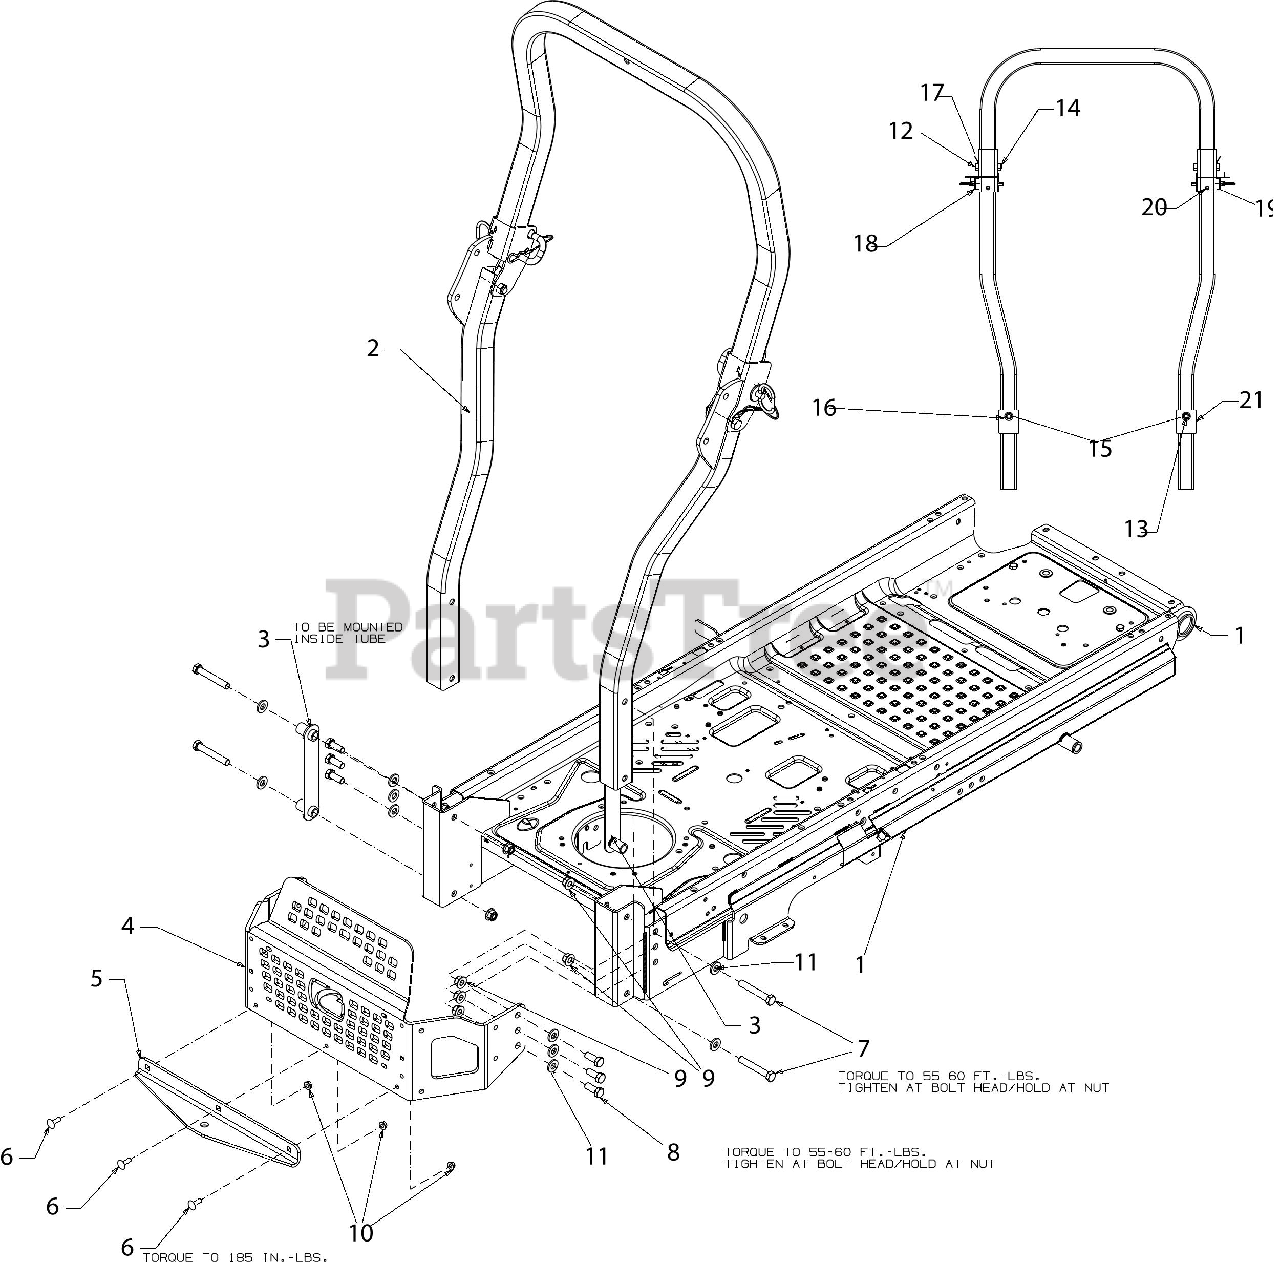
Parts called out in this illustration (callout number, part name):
2	FOLDING ROPS
6	SCREW 5/16-18 X 1.00 GR5
7	SCREW 1/2-13 X 3.25 GR5
8	SCREW 1/2-13 X 1.25 GR5
10	FLANGE NUT
11	FLAT WASHER .531X1.060X.134
12	HEX SCREW HEAD 3.0 x 1/2-13
13	HEX SCREW HEAD 3.5 x 1/2-13
15	WASHER .500
16	U-LOCK-NYLON
17	RETAINING WASHER
18	HITCH PIN
19	FOAM WASHER
20	BUMPER-W/FLANGE
